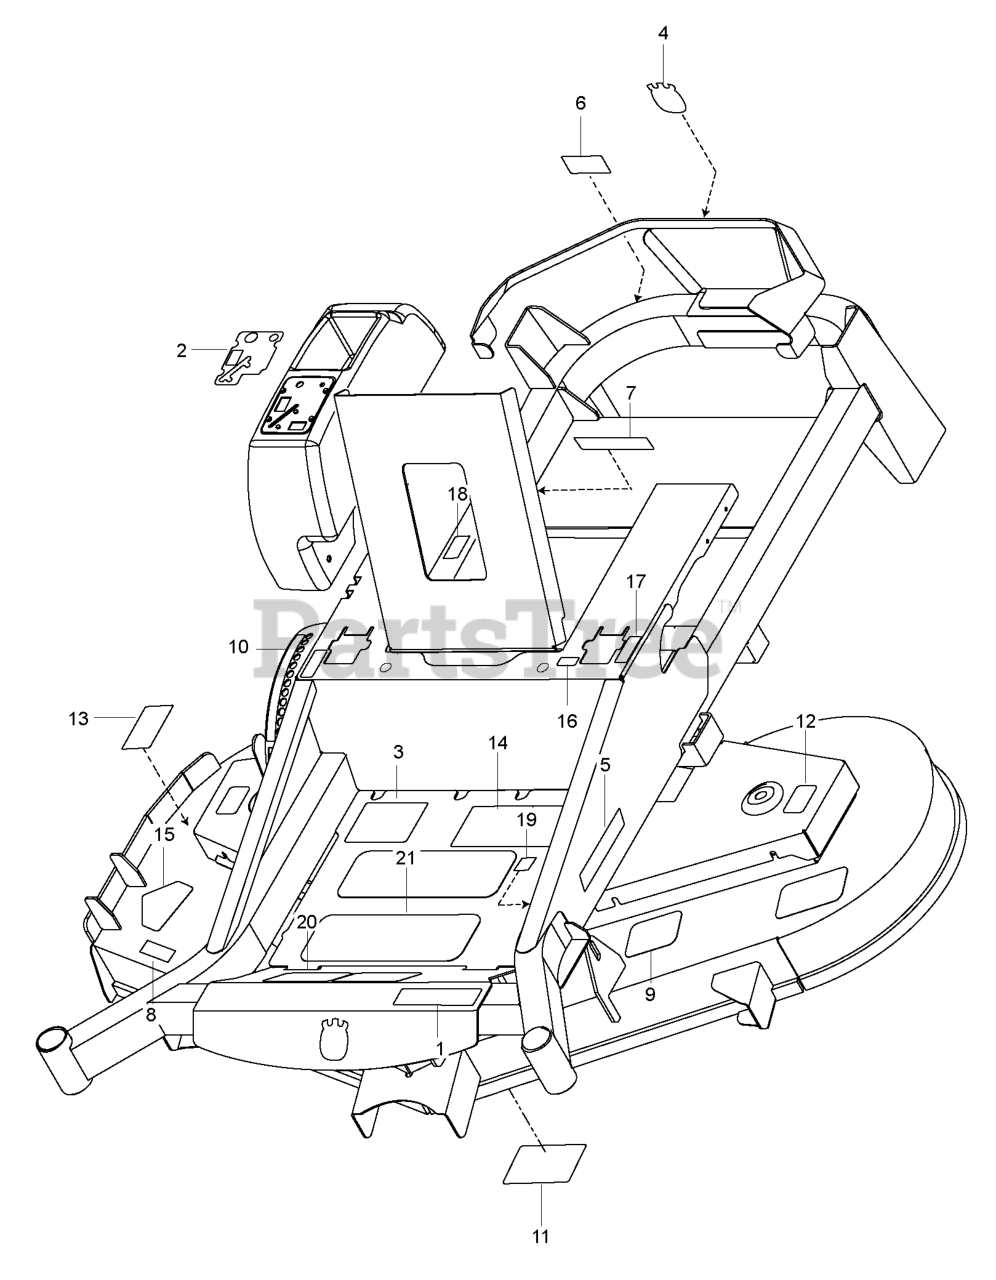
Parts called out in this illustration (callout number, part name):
2	DECAL, CONSOLE HUS
3	DECAL, WARNING
4	DECAL.AUGER.HUSQ.CROWN.SNOW
5	RP.DECAL.BADGE.170MM.TEXTLOGO
6	DECAL, BELT DRIVE
7	EURO DECAL-BATTERY WARNIN6
8	DECAL, EURO SEVERING
9	DECAL, BELT ROUTING
10	DECAL, HEIGHT ADJUST
11	DECAL, SERVICE
12	DECAL, NO STEP
13	DECAL.DECK.6MIL./DEF.SHLD.WARN
14	DECAL.ZTR.WARNING.SMARTIGNITIN
15	DECAL, CPSC
16	DECAL, F.S.T.
17	DECAL, MOTION CONTROL
18	DECAL, ECM, AUSTRALIA
19	DECAL 80 DBA
21	ANTI-SKID PAD
